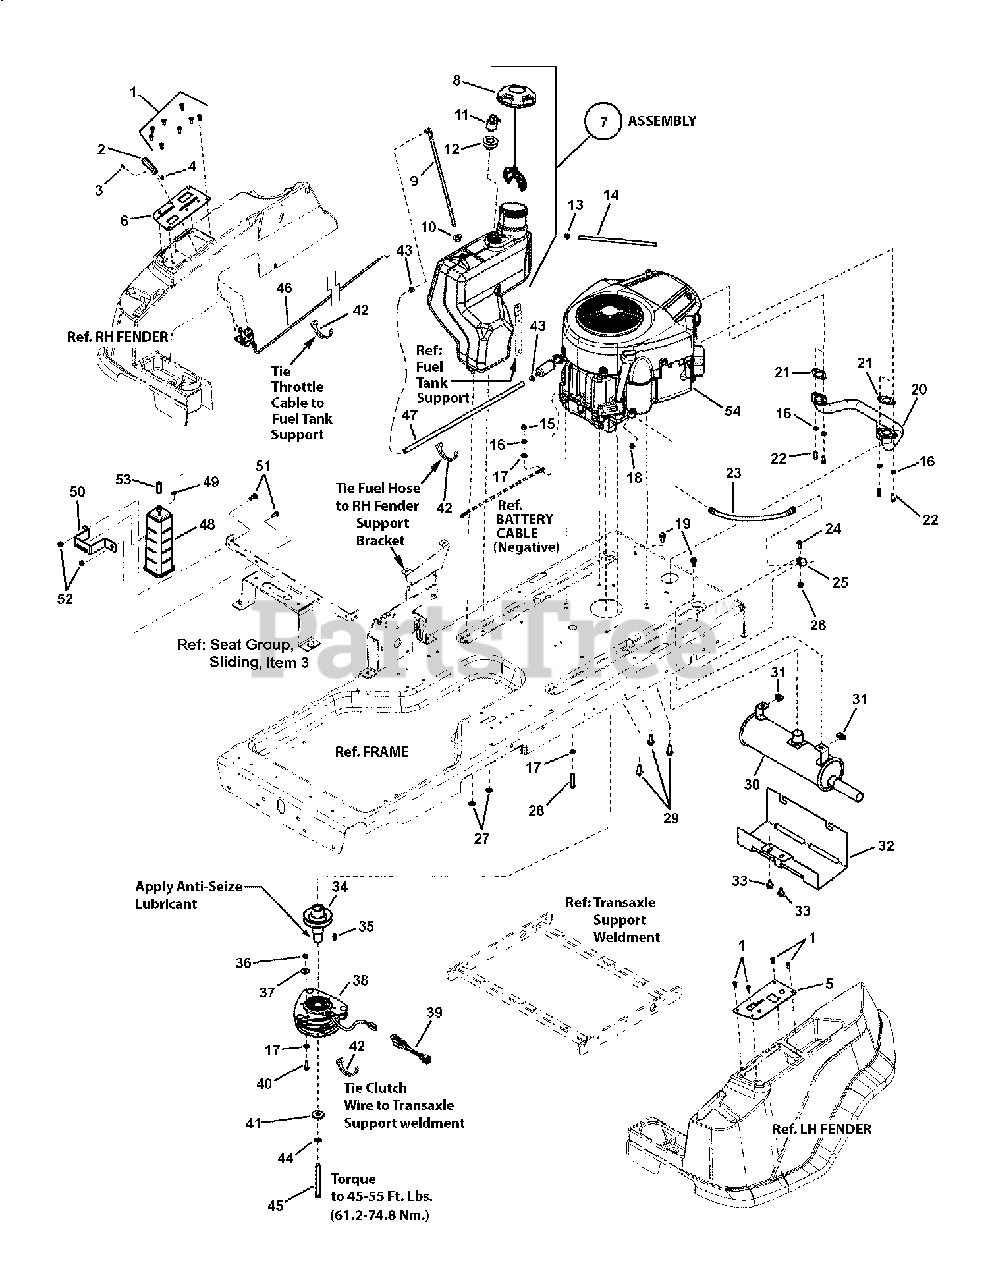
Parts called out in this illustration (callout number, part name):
1	SCREW, 1/4-20 x 5/8" Pan Head Self-Tap (Torx)
2	KNOB, Throttle, Red
3	SCREW, #8-32 x 3/8" Cross Recess Filister Head, GR 2
4	NUT, #8-32 Hex, GR 2B
5	PANEL, Control, LH
6	PANEL, Control, RH
7	ASSEMBLY, Emissions Fuel Tank (incl. 6 items shown below)
8	CAP, Fuel, Emissions, 3-1/2
9	ASSEMBLY, Elbow, Pickup Tube
10	BUSHING, Fuel
11	ASSEMBLY, Remote Vent, No Valve
12	GROMMET
13	HOSE CLAMP, Ctl
14	HOSE, Vapor, (5MM IS x 9MM OD x 16" Long)
15	NUT, 5/16-18 Hex, GR 5 or B, YZ
16	WASHER, 5/16" Split Lock
17	WASHER, 5/16" Flat
18	NUT, 1/4-20 Hex Flange Lock, GR 5, YZ
19	SCREW, 5/16-18 x 3/4" Hex Flange Lock, Black
20	MANIFOLD, B&S V-Twin
21	GASKET, Exhaust B&S Reg (No Chre) 273485
22	SCREW, 5/16-18 x 3/4" Allen Socket Head, GR 8 Black
23	HOSE, Oil Drain
24	SCREW, 5/16-18 x 3/4" Hex Head Cap, GR 5, YZ
25	HARNESS CLIP, 5/8"
26	NUT, 5/16-18 Flange Lock, YZ
27	RETAINER, 3/8" Bolt
28	SCREW, 5/16-18 x 1-3/4" Hex Head Cap, GR 5 YZ
29	SCREW, 3/8-16 x 1" Hex Washer Self-Tap
30	MUFFLER, RZT
31	NUT, Speed, Lug Type, 5/16-18
32	HEAT SHIELD, Muffler
33	SCREW, 3/8-16 x 5/8" Hex Washer Self-Tap
34	ASSEMBLY, Engine Pulley
35	KEY, 1/4" Square x 3/4"
36	NUT, 5/16-18 Hex Center Lock, YZ
37	FENDER WASHER, 5/16"
38	CLUTCH, Ogura JD-11
39	HARNESS, Jumper (used with Ogura Clutch only)
40	SCREW, 5/16-18 x 7/8" Hex Head Cap, GR 5, YZ
41	WASHER, .468 ID x 1-1/2" OD x .188 Flat, YZ
42	CABLE TIE, 7"
43	CLAMP, Fuel Hose
44	WASHER, 7/16" Split Lock, YZ
45	SCREW, 7/16-20 x 4-1/2" Hex Head Cap, GR 5
46	ASSEMBLY, Throttle, B&S V-Twin w/EFM
47	HOSE, Fuel, 1/4" x 32"
48	CANISTER
49	HOSE CLAMP
50	BRACKET, Canister, Vapor
51	BOLT, 1/4-20 x 3/4" Round Head Short Square Neck Carriage, GR 5, YZ
52	NUT, 1/4-20 Hex Nyloc, YZ
53	CAP, Lift Rod
54	* ENGINE, 27HP, B&S Pro, EFM
